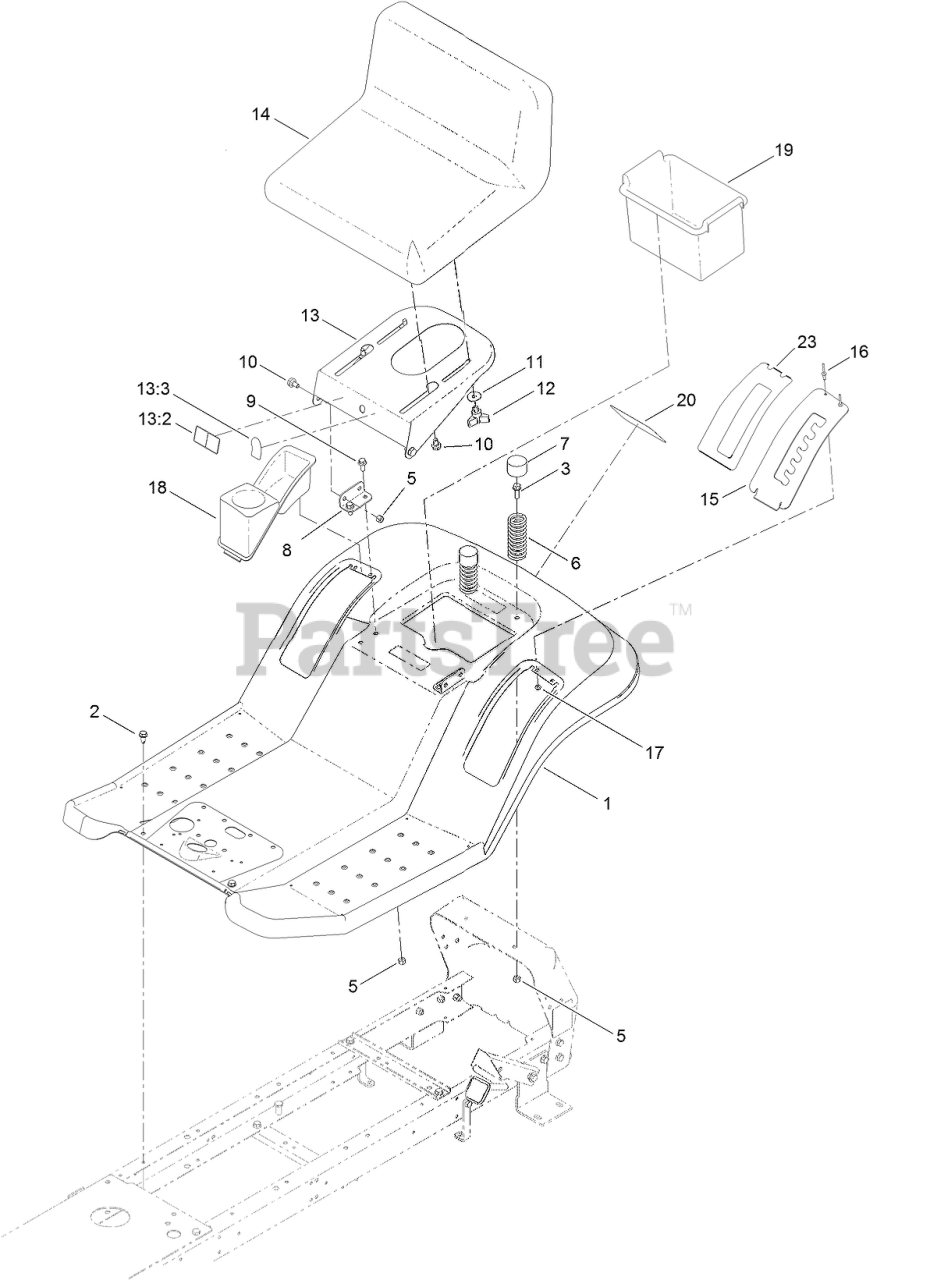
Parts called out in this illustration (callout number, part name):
1	BODY-REAR
2	SCREW-HWH
3	SCREW-HHF
5	NUT-LOCK, NI
6	SPRING-COMPRESSION
7	CAP-PROTECTOR
8	BRACKET-PIVOT, SEAT
9	SCREW-HHF
10	BOLT-SHOULDER
11	WASHER-PIVOT
13	SEAT SUPPORT ASM
13:2	DECAL-DANGER
13:3	DECAL-SWITCH
14	SEAT-11 INCH
15	GATE-HOC
16	RIVET-POP
17	WASHER-PLAIN
18	TRAY-FENDER
19	BOX-BATTERY
20	DECAL
23	DECAL-HOC
